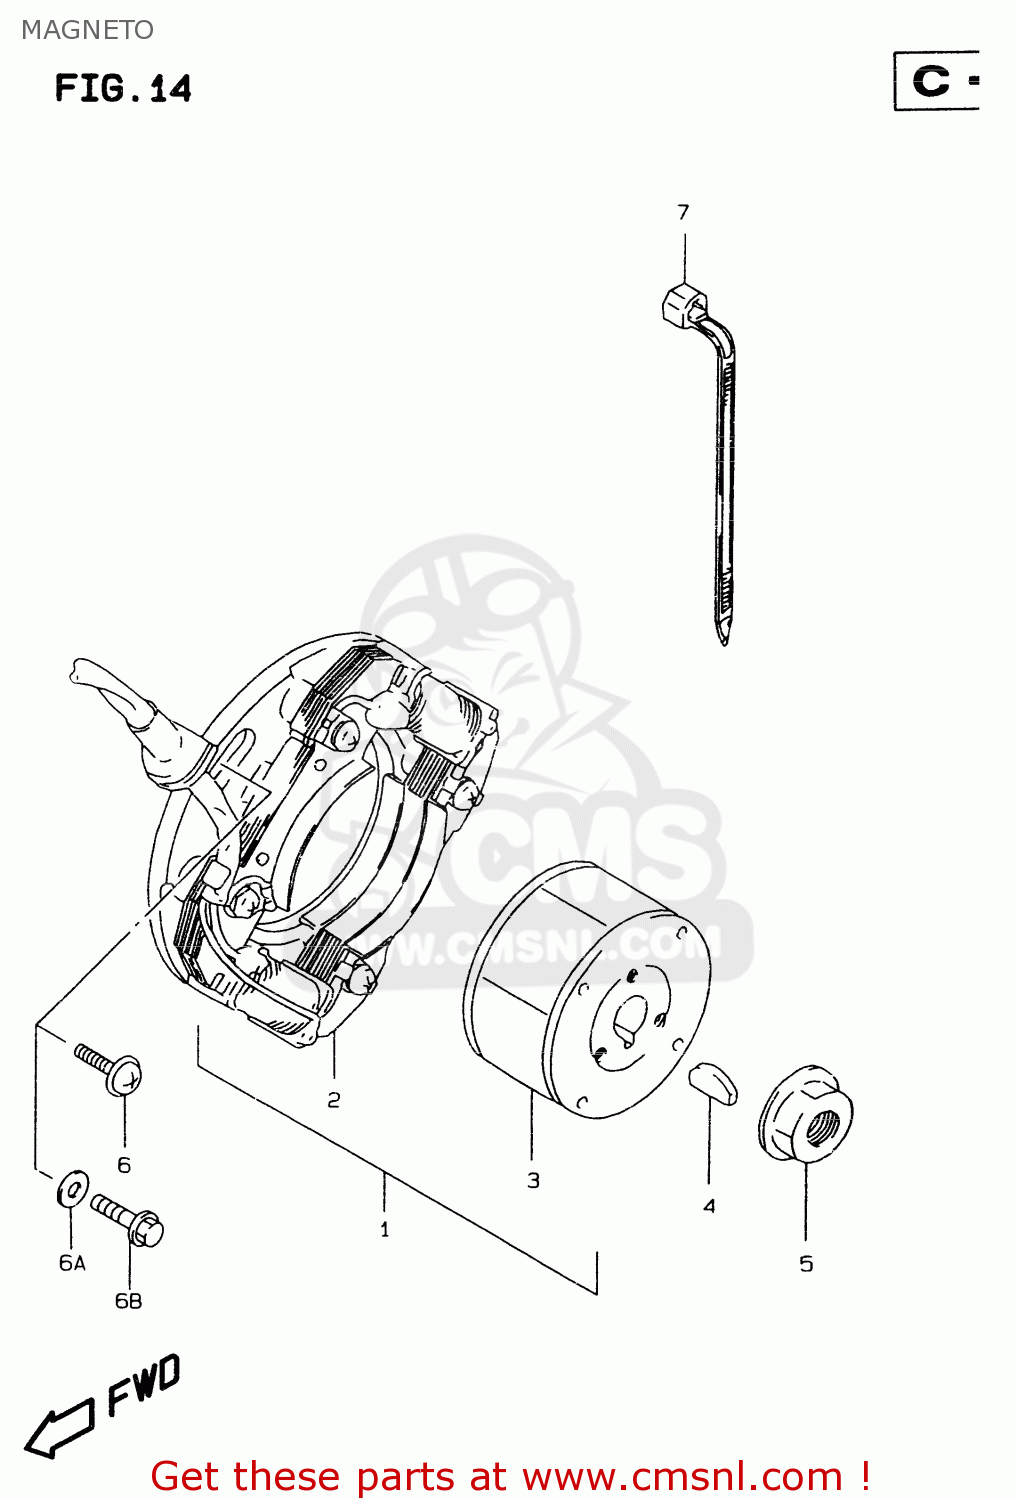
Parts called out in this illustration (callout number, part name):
1	MAGNETO ASSEMBLY
2	STATOR
3	ROTOR
4	KEY
5	NUT
6	SCREW
6A	SCREW
6B	WASHER
7	CLAMP L:165
